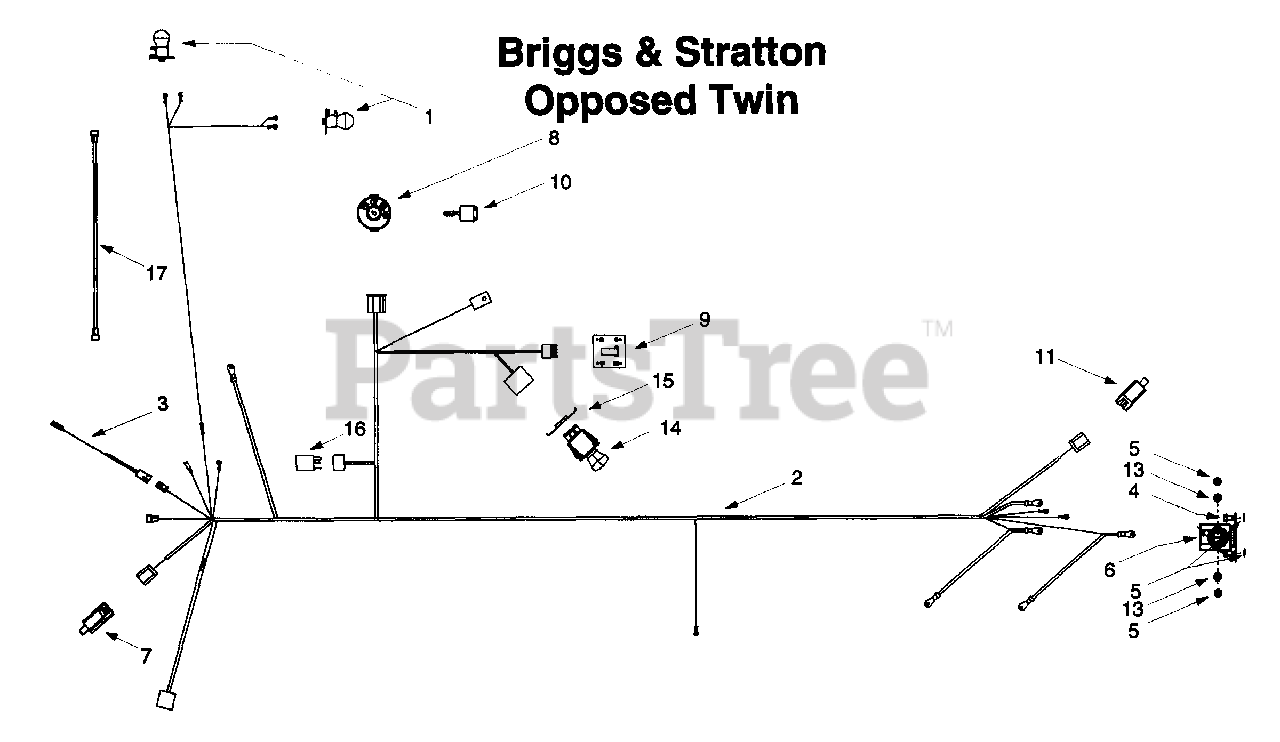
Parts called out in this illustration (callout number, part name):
1	Bulb/Socket Headlight Assembly
2	Wiring Harness
3	Harness Adapter, #18 x 5"
4	Self Tapping Screw, 1/4-20 x .5
5	Hex Nut, 1/4-20
6	Solenoid, 12-volt, 100 Amp
7	Snap Mount Safety Interlock Switch (Brake)
8	Ignition Switch
9	Indicator Monitor w/o Hour Meter
10	Ignition Key W/Plastic Cover
11	Safety Plunger Switch (Seat)
13	Lock Washer, 1/4
14	Electric PTO Switch
15	Retainer Bracket
16	Electric PTO Relay
17	Harness Adapter, 10"
